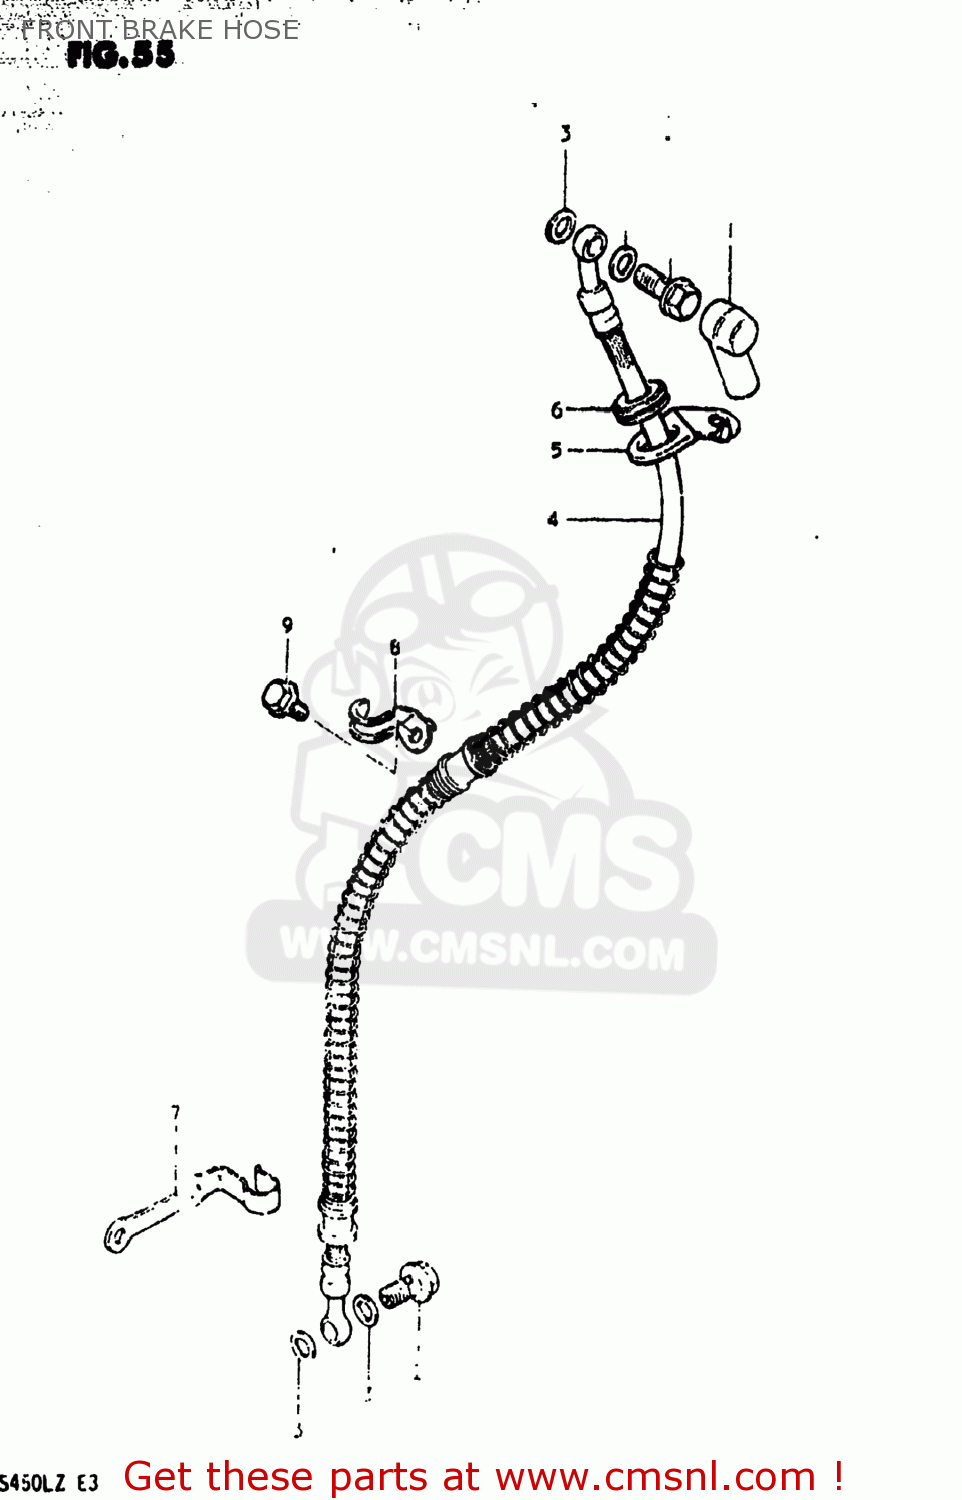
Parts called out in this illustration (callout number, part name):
1	BOOT,MASTER CYLINDER
2	BOLT,UNION
3	WASHER
4	HOSE,FRONT BRAKE
5	GUIDE,BRAKE HOSE
6	GROMMET
7	GUIDE,BRAKE HOSE NO.2
8	GUIDE,BRAKE HOSE NO.3
9	BOLT
